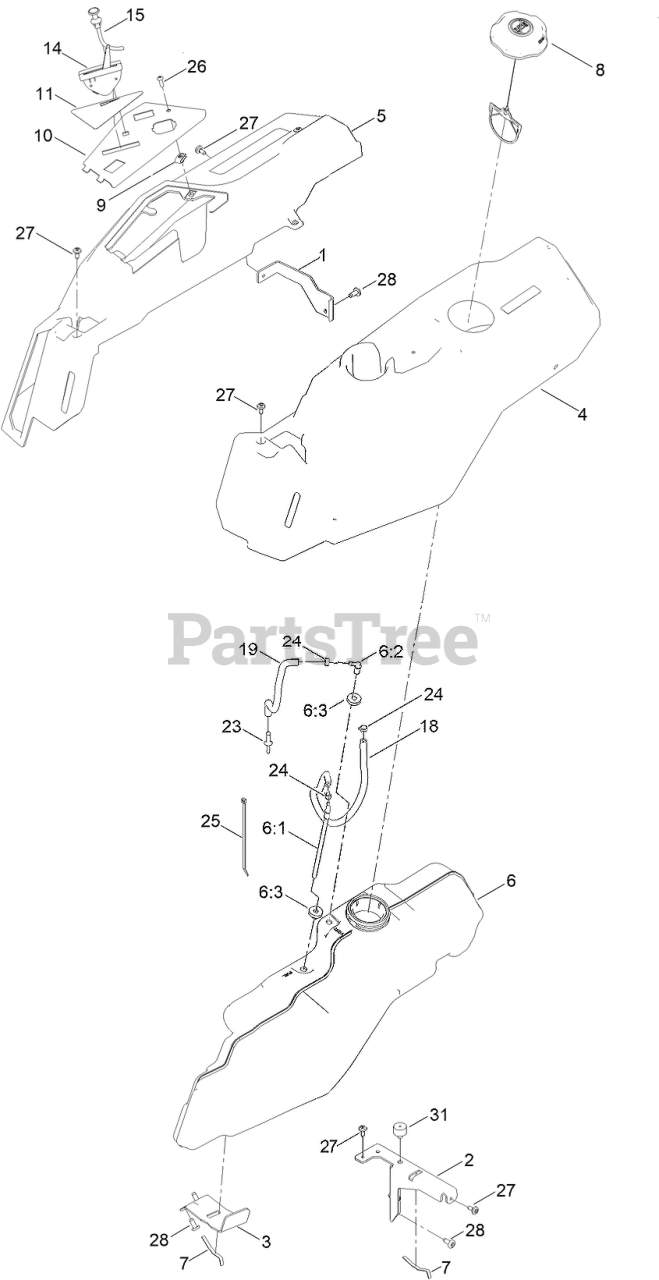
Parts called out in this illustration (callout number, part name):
1	BRACKET-POD
2	SUPPORT-POD, LH
3	SUPPORT-TANK, FUEL
4	POD-LH
5	POD-RH, MYRIDE
6	FUEL TANK ASM
6:1	CONNECTOR-ELBOW, 90 DEG
6:2	FITTING-PLASTIC
6:3	BUSHING
7	SPRING
8	CAP-FUEL, RATCHETING
10	PANEL - CONTROL
11	DECAL-PANEL, CONTROL
14	CABLE-THROTTLE
15	CABLE-CHOKE
18	HOSE-FUEL
19	HOSE-FUEL
23	ADAPTOR-ORIFICE
24	CLAMP-HOSE
25	TIE-CABLE
26	SCREW-PRH
27	SCREW-SHOULDER
31	BUMPER-GROMMET
